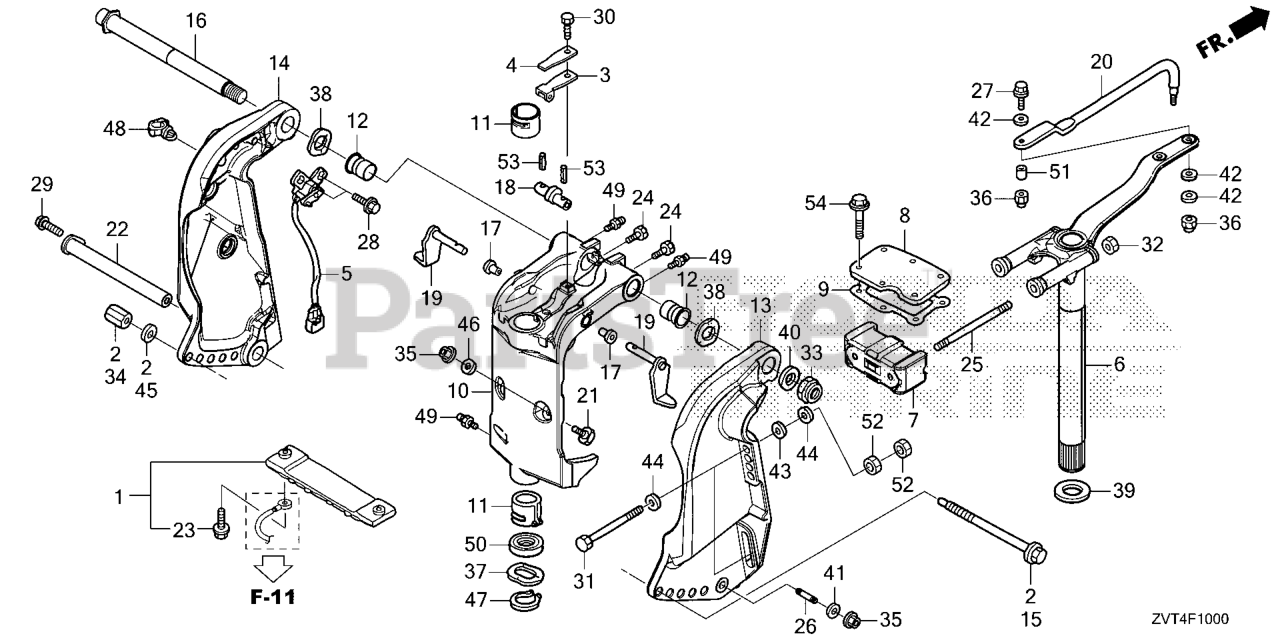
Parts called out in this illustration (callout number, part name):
1	METAL KIT, ANODE Use from Frame SN 4800343.
2	ROD, ADJUSTING
3	SPRING, CLICK
4	SPRING, CLICK ASSIST
5	SENSOR ASSY., TRIM ANGLE
6	FRAME, MOUNT
7	MOUNT, RUBBER (UPPER)
8	HOLDER, MOUNTING (UPPER)
9	GASKET, MOUNTING HOLDER (UPPER)
10	CASE, SWIVEL *NH565*
10	CASE *NHB14M*
11	LINER, SWIVEL CASE
12	BUSH, SWIVEL CASE
13	BRACKET *NH565*
13	BRACKET *NHB14M*
14	BRACKET *NH565*
14	BRACKET *NHB14M*
15	ROD, ADJUSTING
16	SHAFT, TILTING
17	BUSH, TILT ARM
18	BRACKET, TILTING
19	STOPPER, TILT
20	ROD, STEERING
21	RECEIVER, THRUST
22	SHAFT, CYLINDER (LOWER)
23	BOLT, FLANGE (6X23) Use from Frame SN 4800343.
24	BOLT (1/4-28UNF)
25	BOLT, STUD (12X145)
26	BOLT, STUD (10X28)
27	BOLT (3/8-24UNF)
28	BOLT, FLANGE (6X20) (ENGINE NO.)
29	BOLT, FLANGE (8X22)
30	BOLT, HEX. (6X14)
31	BOLT, HEX. (12X130)
32	NUT, FLANGE (12MM)
33	NUT, SELF-LOCK (7/8-14UNF)
34	NUT, ADJUSTER ROD
35	NUT, FLANGE (10MM)
36	NUT, SELF-LOCK (3/8-24UNF)
37	WASHER, WAVE (40MM)
38	WASHER, WAVE (26MM)
39	WASHER, THRUST (34MM)
40	WASHER (7/8")
41	WASHER, PLAIN (10MM)
42	WASHER (10MM)
43	WASHER, PLAIN (12MM)
44	WASHER, PLAIN (12MM)
45	WASHER, PLAIN (12MM)
46	WASHER, PLAIN (10MM)
47	CIRCLIP (OUTER) (39MM)
48	CLIP, WIRE HARNESS
49	NIPPLE, GREASE
50	OIL SEAL (39.5X52X6) (ARAI)
51	COLLAR, STEERING ROD
52	NUT, HEX. (12MM)
53	PIN, SPRING (2.5X20)
54	BOLT, FLANGE (8X35)
